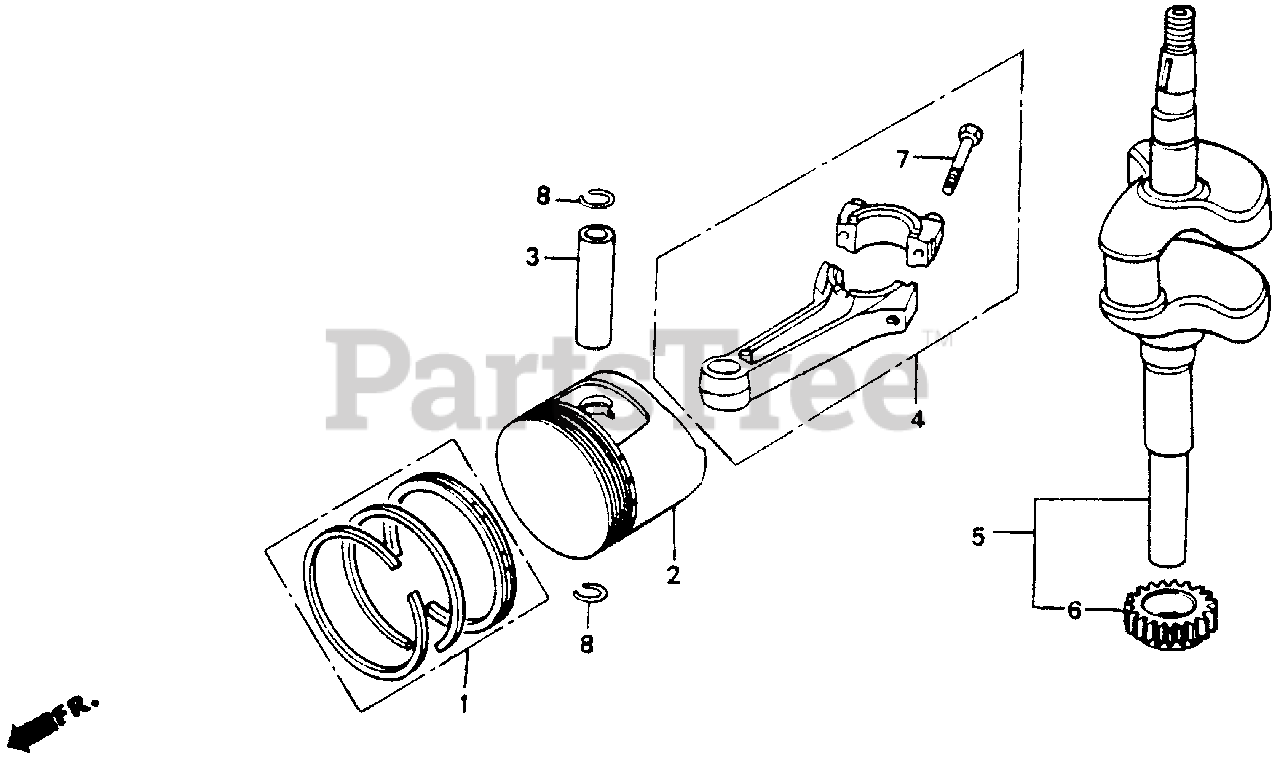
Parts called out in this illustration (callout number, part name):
1	RING SET, PISTON (STD)
1	RING SET, PISTON (OS 0.25) Use up to Engine SN 2147021.
1	RING SET, PISTON (OS 0.25)
1	RING SET, PISTON (OS 0.50) Use up to Engine SN 2147021.
1	RING SET, PISTON (OS 0.50)
1	RING SET, PISTON (0.75) Use up to Engine SN 2147021.
1	RING SET, PISTON (0.75)
2	PISTON (STD)
2	PISTON (OS 0.25) Use up to Engine SN 2147021.
2	PISTON (OS 0.25) Use from Engine SN 2147022.
2	PISTON (OS 0.50) Use up to Engine SN 2147021.
2	PISTON (OS 0.50) Use from Engine SN 2147022.
2	PISTON (0.75) Use from Engine SN 1199575 to 2147021.
2	PISTON (0.75) Use up to Engine SN 2147021.
2	PISTON (0.75) Use from Engine SN 2147022.
3	PIN, PISTON
4	ROD ASSY., CONNECTING Use up to Engine SN 2250472.
4	ROD ASSY., CONNECTING
4	ROD ASSY., CONNECTING Use from Engine SN 2250473.
5	CRANKSHAFT
6	GEAR, TIMING
7	BOLT, CONNECTING ROD
8	CLIP, PISTON PIN (13MM)
